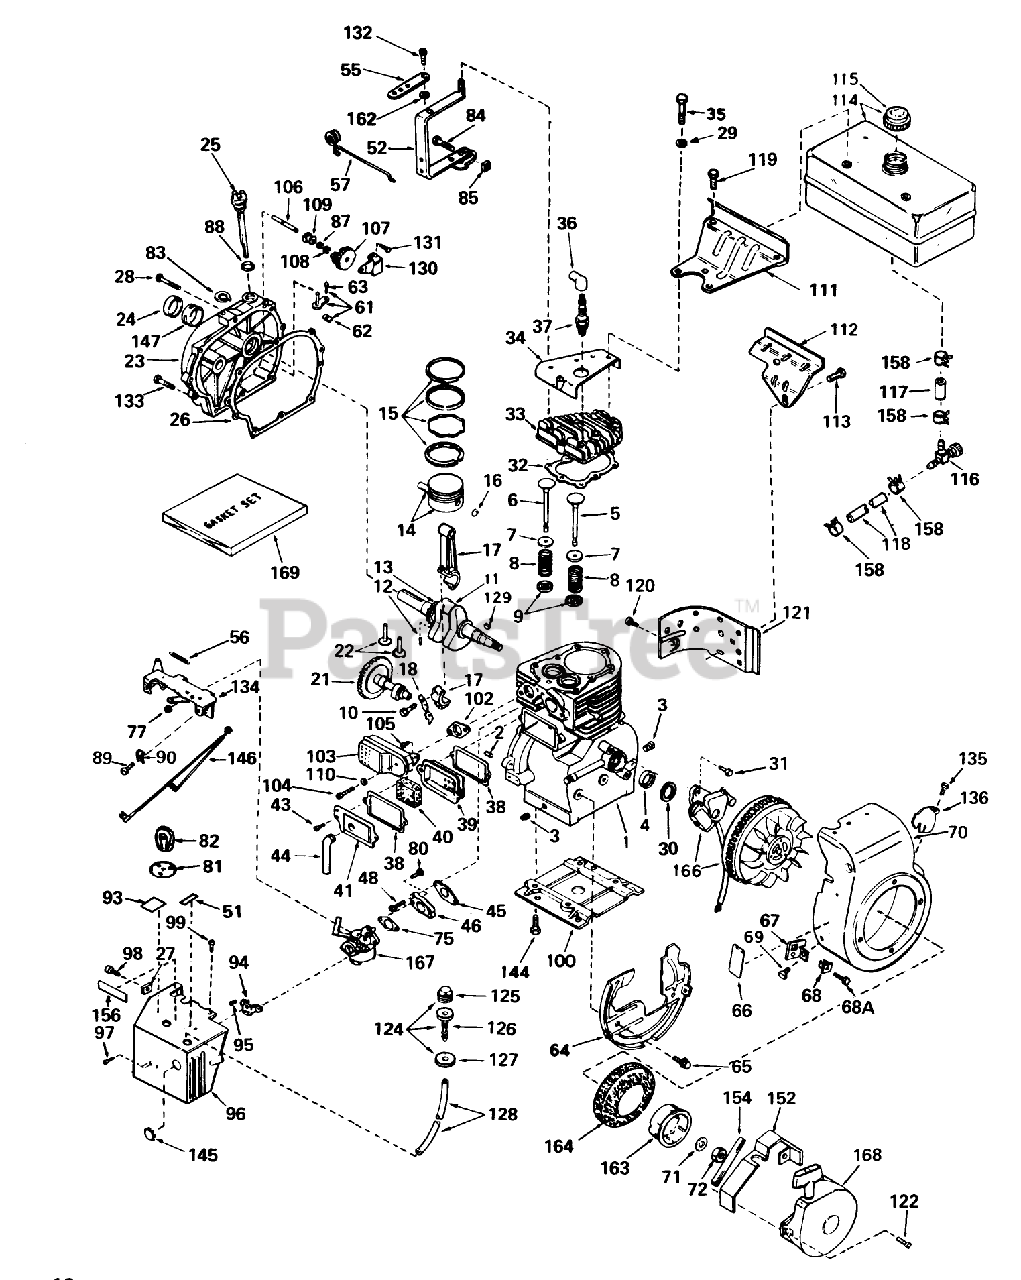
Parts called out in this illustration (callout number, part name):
1	Cylinder Assy. (Incl. Nos. 2, 3 4)
2	Pin-Dowel
3	Plug-Drain, Oil (SQH 1/4-18)
4	Oil Seal
5	Valve, Intake (Standard)(Incl. No. 9)
5	Valve, Intake (1/32" oversize)(Incl. No. 9)
6	Valve, Exhaust (Standard)(Incl. No. 9)
6	Valve, Exhaust (1/32" oversize)(Incl. No. 9)
7	Cap-Spring, Valve
8	Spring-Valve
9	Keeper-Spring, Valve
10	Screw, Hex Hd.
11	Crankshaft Assy. (Incl. Nos. 12 13)
12	Pin, Groove
13	Gear-Crankshaft
14	Piston Pin Assy. (Incl. 2 of No. 16)(Standard)
14	Piston Pin Assy. (Incl. 2 of No. 16)(.010 oversize)
14	Piston Pin Assy. (Incl. 2 of No. 16)(.020 oversize)
15	ORing
15	Ring Set (.010" OS)
15	Ring Set (.020" OS)
17	Rod Assy., Connecting (Incl. Nos. 10 18)
18	Plate, Lock
21	Camshaft
22	Lifter-Valve
23	Cover, Cylinder (Incl. Nos. 24 106)
24	Oil Seal
25	Dipstick, Oil (Incl. No. 30)
26	Gasket-Cover, Cylinder
27	Nut-U Type
28	Screw (1/4-20 x 1-1/4)
29	Washer-Flat
30	Gasket Stator
31	Screw
32	Gasket-Cylinder Head
33	CYLINDER HEAD
34	Cover-Head, Cylinder
35	Screw Hex Hd. Cap
36	Cover-Spark Plug
37	Plug, Spark (Champion RCJ8 or Autolite AR7N Resistor type)
38	Gasket-Breather
39	Body-Breather
40	Element-Breather
41	Cover-Valve
43	Screw
44	Tube-Breather
45	Gasket-Intake
46	Flange, Carburetor (Incl. Nos. 77 80)
48	Screw
51	Decal-Primer
52	Lever, Governor
56	Spring, Extension
57	Link, Governor to Throttle
61	Rod, Governor (Incl. Nos.62 63)
62	Yoke-Governor
63	Screw (6-40x5/16)
64	Baffle Blower Housing
65	Screw (1/4-20x19/32)
66	Decal, Instruction
67	Bracket
68	Grommet
68A	Screw
69	Screw, Hex Hd.
70	Housing, Blower (Incl. Nos.135 136)
71	Washer
75	Gasket-Carburetor
77	Nut and Lock Washer (1/4-28)
80	Screw
81	Plate, Control
82	Knob-Control
83	Ring-Retaining
84	Screw
85	Nut-Lock
87	Washer-Flat
88	Gasket
89	Screw (10-32 x 3/8)
90	Conduit
93	Decal, Warning
94	Bracket-Choke
95	Screw (10-32 x 1/2)
96	Cover, Carburetor
97	Screw (8-32 X 5/16)
98	Screw (8-32 x 3/8)
99	Screw (10-32x1/2)
100	Base Engine
102	Gasket Exhaust
103	Muffler
104	Screw Hex Hd. Cap
105	Screw
106	Shaft-Governor
107	Governor Gear ASM
108	Ring-Retaining
109	Spool-Governor
110	Washer
111	Bracket-Fuel Tank
112	Bracket-Fuel Tank
113	Screw (1/4-20x19/32)
114	Tank Assy., Fuel (Incl. No. 115)
115	Cap, Fuel
116	Valve-Shut Off
117	Line-Fuel (8.62)
118	Line-Fuel
119	Screw (1/4-15x7/8)
120	Screw
121	Emnsion, Blower Housing
122	Screw
124	Primer Assy. (Incl. Nos. 89, 90 91)
125	Bulb, Primer
126	Body, Primer
127	Retainer, Primer Bulb
128	Line, Primer
129	Key-Flywheel
130	Bracket, Governor
131	Screw (10-32 x 35/64)
132	Screw
133	Screw
134	Bracket Assy., Speed Control (Incl. No. 56)
135	Screw, Pan Hd.
136	Screw
144	Screw
145	Plug
146	Wire, Ground
147	Bushing-Crankshaft
152	Guard-Starter
154	Seal, Snowguard
156	Decal, Choke
158	Clamp-Line, Fuel
162	Washer-Lock
163	Cup-Starter
164	Screen, Air
166	Magneto
167	Carburetor (Incl. No. 75)
168	Starter Assy., Rewind
169	Gasket Set
